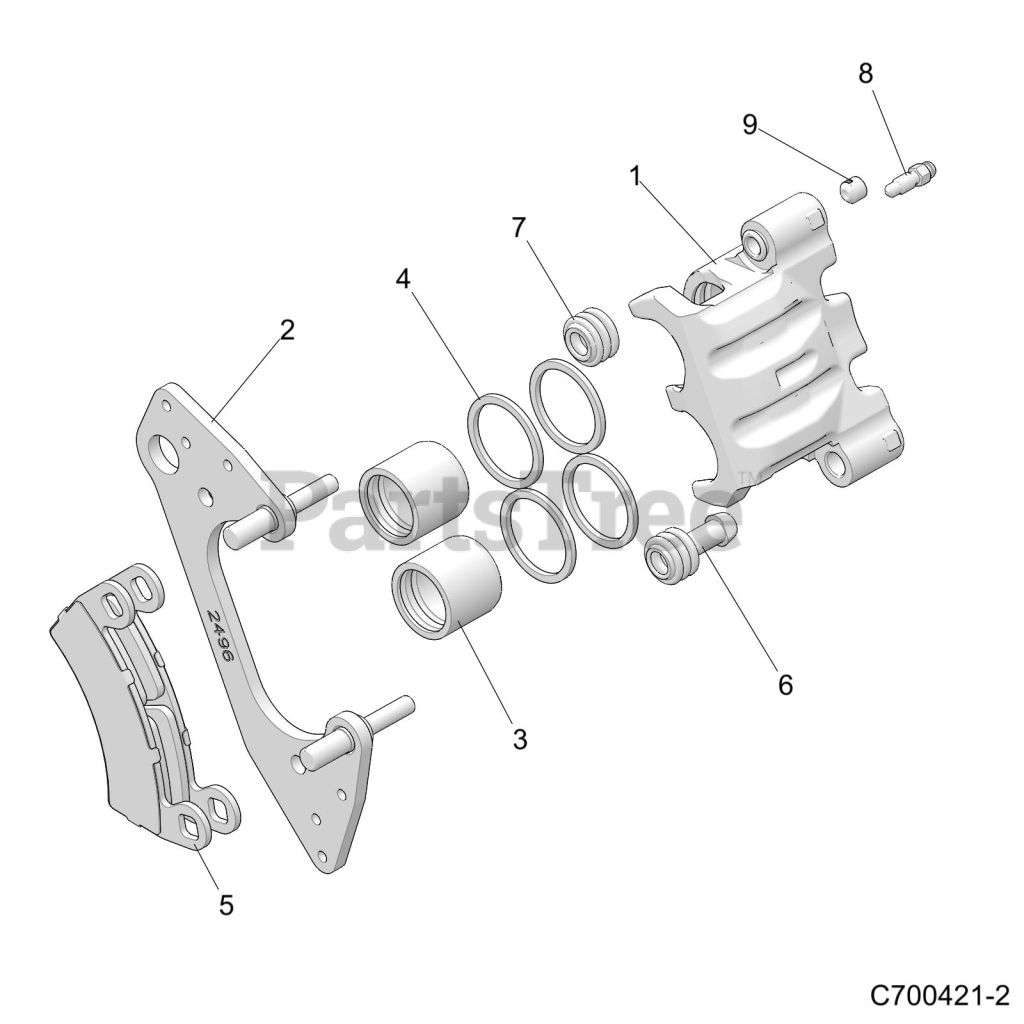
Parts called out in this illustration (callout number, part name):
1	ASM-BRK-CAL-L-DB1-3/8-GROOVED
1	ASM-BRK-CAL-R-DB1-3/8-GROOVED
2	ASM-CAL/MNT,DB,1-3/8,METRIC
3	PISTON-BRAKE,1.375,AL,GROOVED
4	SEAL-CALIPER,INNER,1.375"
5	KIT-ASM,PAD,BRAKE,DB,1.375
6	BOOT-PIN BUSHING
7	BOOT-PIN SEAL
8	SCR-M7X1.0,BLEEDER,OLIVE D
9	SCR-M10X1.0X8,SOC SET-OD
